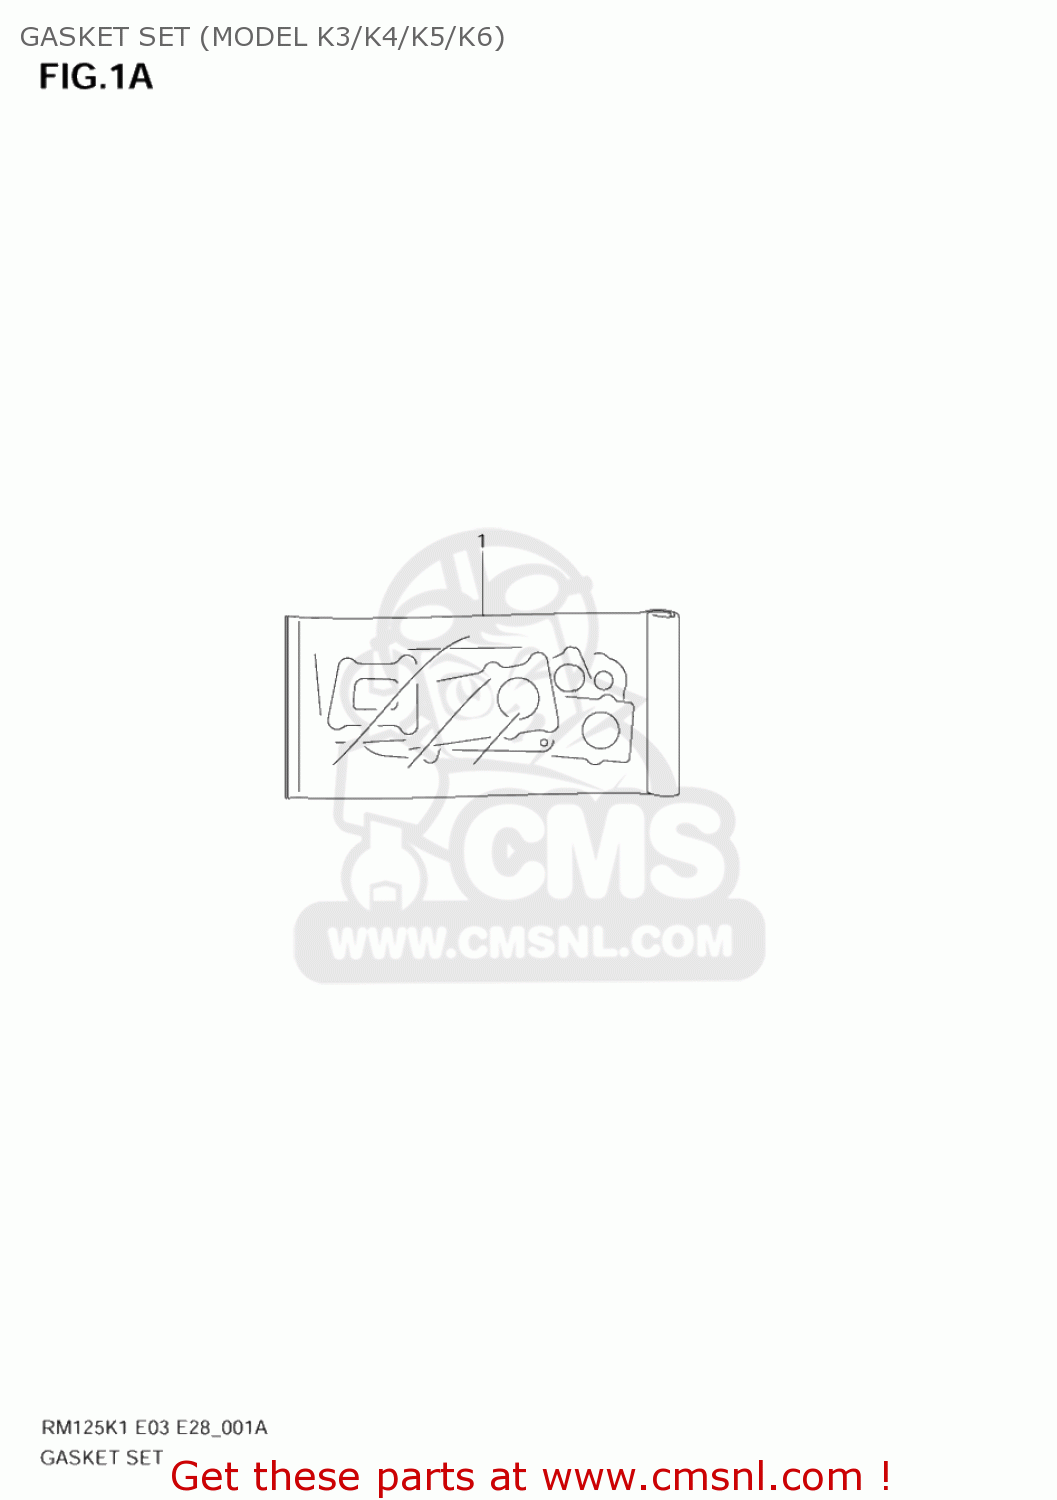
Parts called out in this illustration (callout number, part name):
1	GASKET SET (NAS)
2	O RING,CYLINDER HEAD NO.1
3	O RING,CYLINDER HEAD NO.2
4	GASKET,CYLINDER COVER NO.1 (NAS)
5	GASKET,CYL COVER NO.2
6	GASKET,CYLINDER (NAS)
7	GASKET,CRANKCASE (NAS)
8	GASKET,CLUTCH COVER (NAS)
9	GASKET,MAGNETO COVER
10	O RING,CLUTCH COVER OUTER
11	O RING,EXHAUST PIPE
12	WASHER,EXHAUST PIPE
13	CONNECTOR,MUFFLER
14	GASKET,WATER PUMP CASE (NAS)
15	GASKET(12.1X16.2X3.7) (NAS)
16	O RING(D:1.9,ID:22.6)
